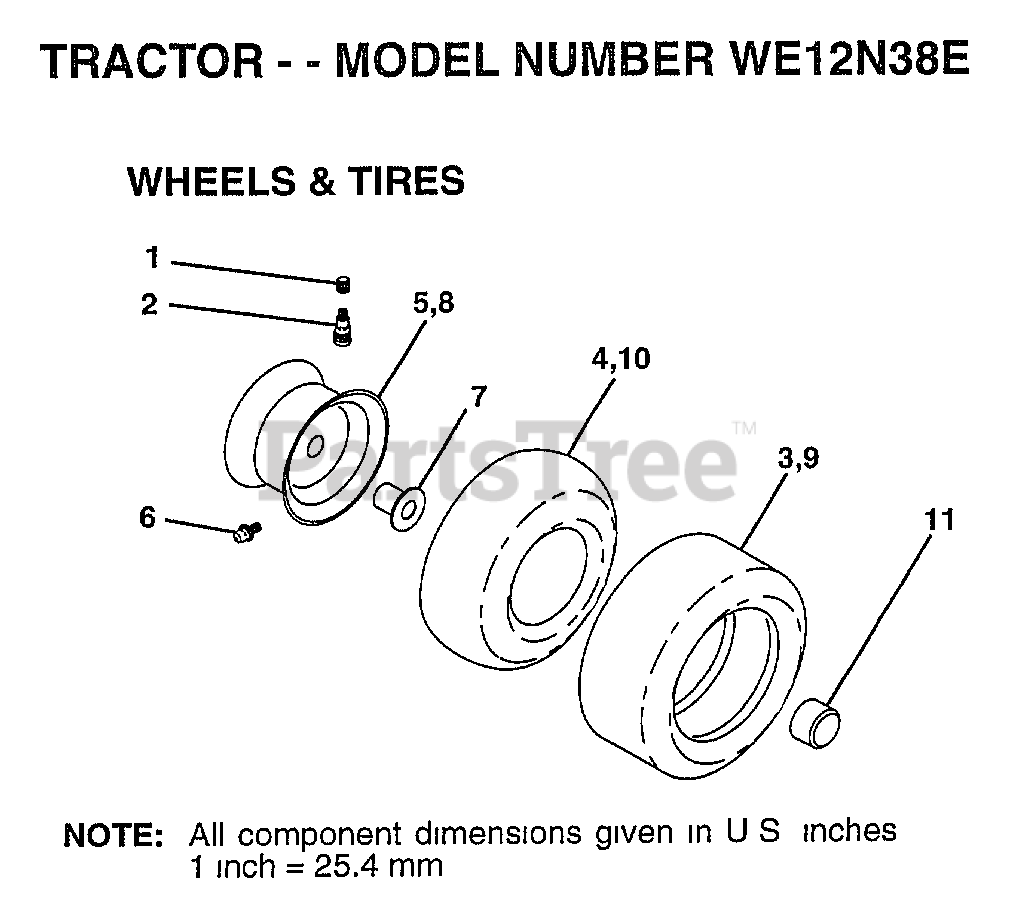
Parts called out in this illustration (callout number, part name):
1	VALVE CAP
2	VALVE STEM LT
4	TUBE.5.3/4.5/6
5	RIM.FRONT.6.YELLO
6	FITTING LT
7	"FLANGE, BEARING"
10	TUBE.18X9.5-8
11	HUB CAP
